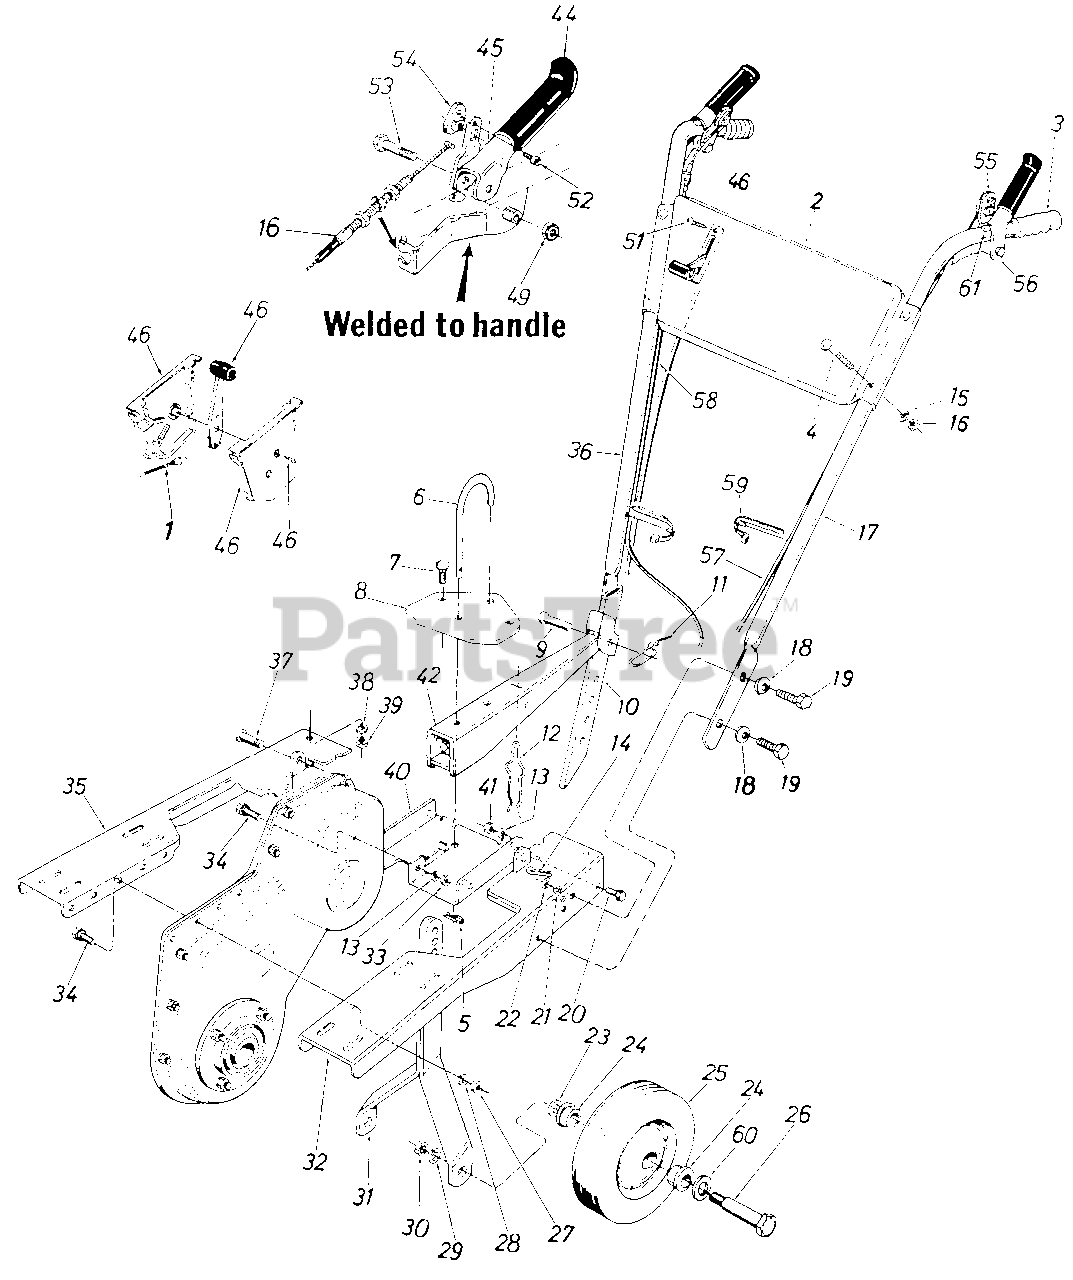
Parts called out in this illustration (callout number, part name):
1	WIRE-CONTROL
2	PANEL-HANDLE
3	GRIP-BLACK
4	BOLT-CARRIAGE 5/16-18 X 1.75
5	PIN-COTTER
6	PIN-CLEVIS .50 DIA
7	BOLT-CARRIAGE 5/16-18 X .75
8	PLATE-U CHANNEL
9	PIN-CLEVIS
10	BAR-DEPTH
11	PIN-SPRING
12	SPRING-DEPTH BAR
13	WASHER-LOCK-5/16
14	PIN-COTTER
15	WASHER-LOCK-5/16
16	NUT-HEX 5/16-18
17	HANDLE-LH
18	WASHER-BELL .400 ID X .88 X .060
19	SCREW-HEX 3/8-16 X 1.00
20	SCREW-HEX 5/16-18 X .75
21	WASHER-LOCK-3/8
22	NUT-HEX 3/8-16
23	WASHER-BELL .505 ID X 1.00 OD
24	BEARING-FLANGE
25	WHEEL ASSY-10 X 1.75
26	SCREW-SHLD
27	NUT-HEX 5/16-18
28	WASHER-LOCK-5/16
29	WASHER-LOCK-1/2
30	NUT-HEX INS L-1/2-20
31	BRACKET ASSY-WHL
32	CHANNEL ASSY-U-LH
33	NUT-HEX 5/16-18
34	SCREW-HEX SEMS 5/16-18 X 1.00
35	CHANNEL-ENG U
36	HANDLE ASSY-RH
37	PIN-CLEVIS
38	WASHER-LOCK-5/16
39	NUT-HEX 5/16-18
40	BRACKET ASSY-U CHANNEL
41	NUT-HEX 5/16-18
42	TAIL PIECE ASSY
45	GRIP ASSY-CLUTCH-RH
46	CONTROL-THROTTLE
49	NUT-HEX INS L-3/8-24
51	SCREW-TRUSS TAP
52	SCREW-TAP
53	SCREW-HEX 3/8-24 X 2.00
54	HOLD DOWN-BARREL-RH
55	HOLD DOWN-CABLE
56	GRIP ASSY-LH
57	CABLE-CLUTCH CONTROL
58	CABLE-CLUTCH CONTROL
59	TIE-CABLE
60	WASHER-FL-.640ID X 1.24OD X .06HDN
61	CAP-PUSH
